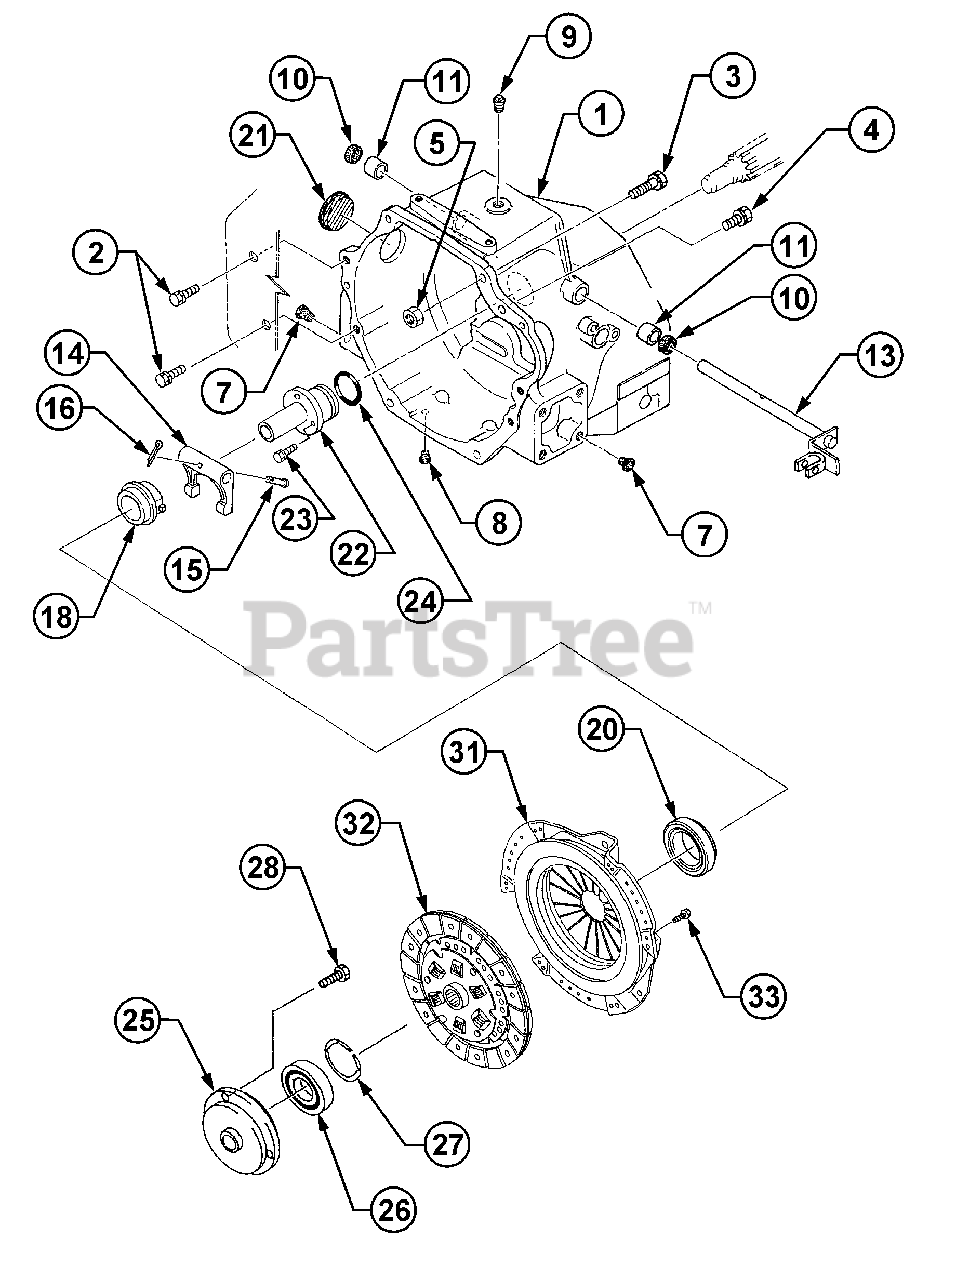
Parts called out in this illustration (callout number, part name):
1	Housing Clutch
2	Bolt, w/Washer
3	Bolt, w/Washer
4	Bolt, w/Washer
9	Breather, Air
13	Shaft, Release
14	Lever, Release
16	Pin, Split
23	Bolt, w/Washer
26	Bearing, Ball
33	Bolt, w/Washer
